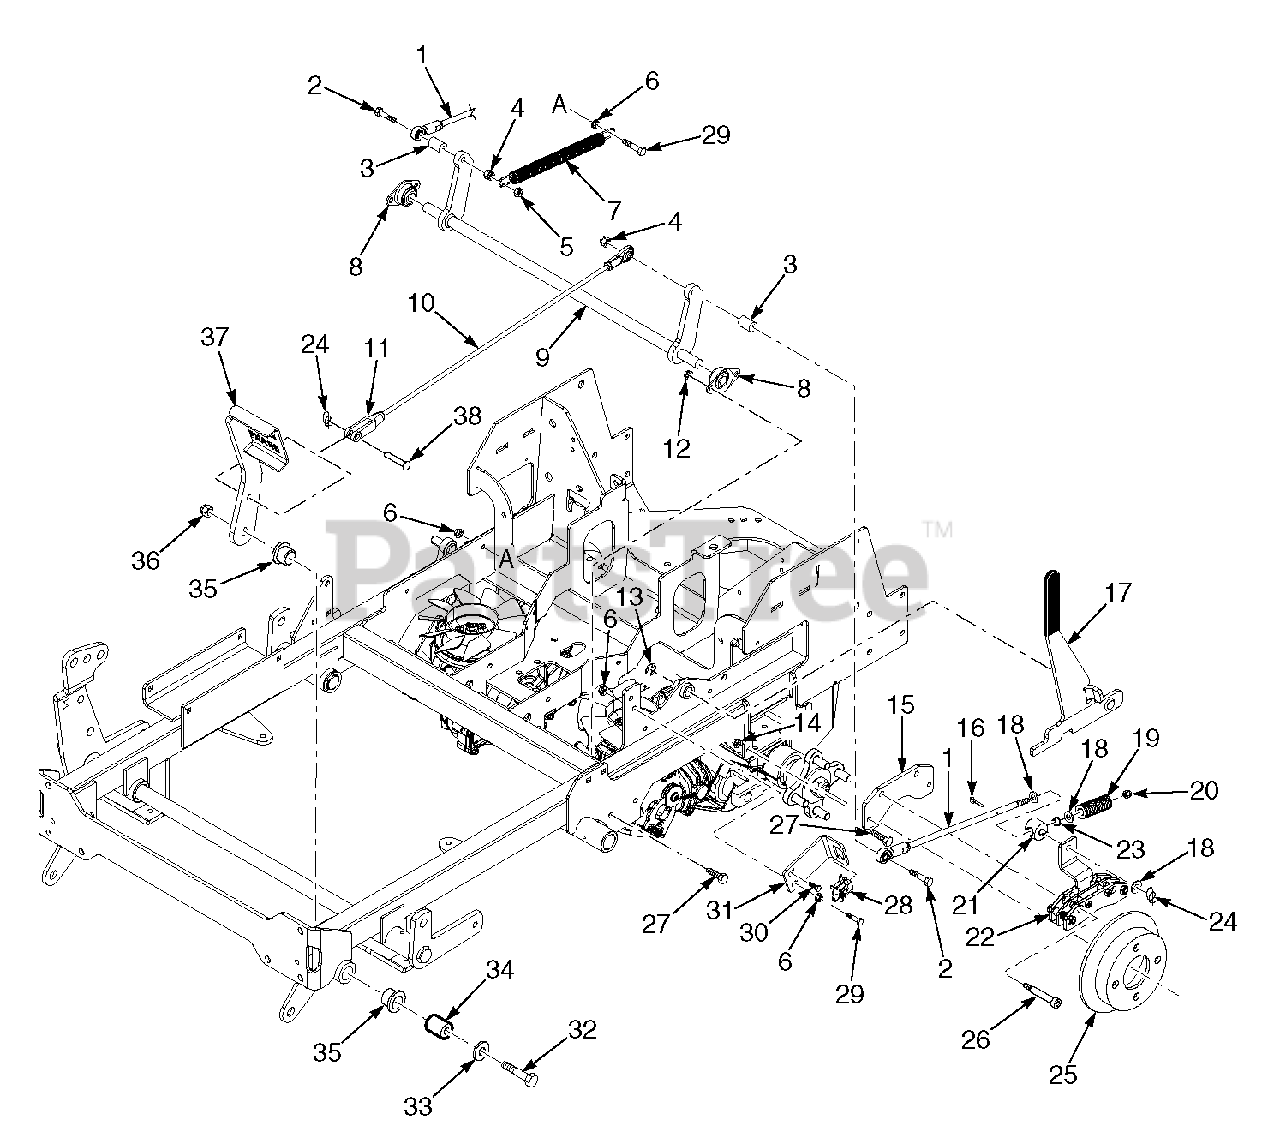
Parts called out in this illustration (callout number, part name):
1	Brake Link Assembly
2	Bolt, Hex Head 3/8-16 x 3"
3	Spacer
4	Nut, Elastic Stop 3/8-16
5	Nut, Center Lock 3/8-16
6	Nut, Serrated Flange 1/4-20
7	Spring, Brake Return
8	Bearing, Self Align - 5/8" I.D.
9	Brake Bellcrank Weldment
10	Brake Rod Assembly
10	Rod End, 3/8-24 LH
10	Nut, 3/8-24 UNF LH Jam
11	Clevis
11	Nut, 3/8-24 UNF Jam
12	Nut, Elasticc Stop 5/16-18
13	Retaining Ring, .625 Ext "E"
14	Nut, Serrated Flange 5/16-18
15	Mounting Bracket, Brake
16	Cotter Pin, 3/32 x 3/4"
17	Lever w/Grip, Parking Brake
17	Grip, Brake Lever
18	Flatwasher, 3/8-.406 x .812 x .065
19	Spring, Brake
20	Nut, Elastic Stop 3/8-24
21	Swivel Assembly, Brake
22	Brake Caliper
23	Bearing
24	Pin, Rue Cotter - 3/8" Dia.
25	Brake Hub
26	Bolt, 1/2 x 2-3/4" Shoulder
27	Bolt, Hex Head 5/16-18 x 3/4"
28	Switch
29	Bolt, Hex Head 1/4-20 x 1-1/4"
30	Bolt, Carriage 1/4-20 x 1/2"
31	Switch Mounting Bracket, Brake
32	Bolt, Hex Head 1/2-13 x 4-1/4"
33	Flatwasher, 1/2-.562 x 1.375 x .109
34	Sleeve, Brake Pivot
35	Bearing
36	Nut, Elastic Stop 1/2-13
37	Brake Pedal Weldment
38	Clevis Pin, 3/8 x 1.06"
